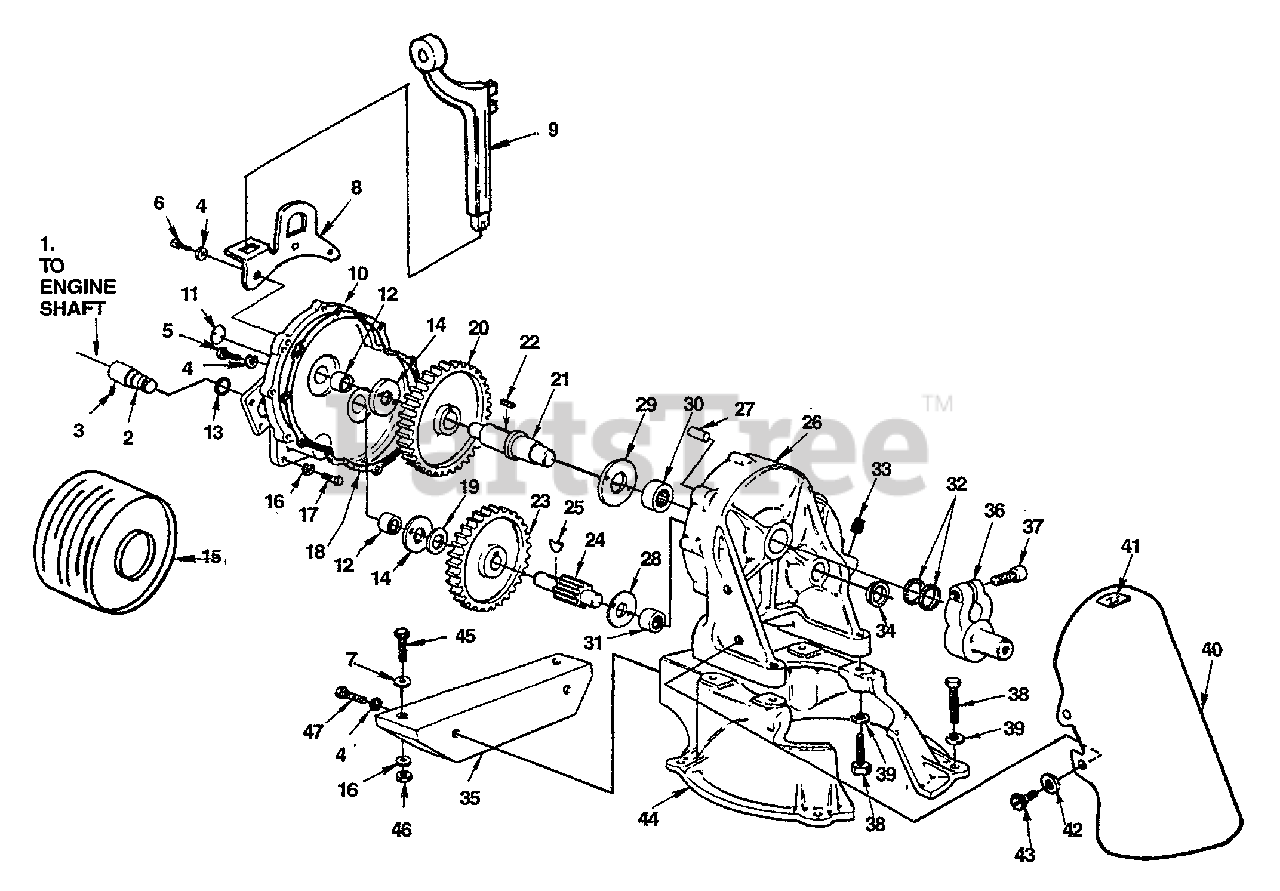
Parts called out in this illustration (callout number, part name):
2	SHAFT - Extension
3	SCREW - set 5/16-18 x 3/8
4	WASHER - lock, 1/4
5	SCREW - hex hd., 1/4-20 x 1
6	SCREW - hex hd.,1/4-20 x 1 1/4
7	WASHER, flat - 5/16
8	BRACKET, lifting
9	WRENCH - Spanner
10	GEAR CASE COVER
11	CAP, bearing
12	BEARING, Needle
13	SEAL, extension shaft
14	WASHER, thrust
15	STRAINER
16	WASHER, lock 5/16
17	SCREW, hex hd., 5/16-24 x 7/8
18	GASKET, gear case
20	GEAR, pump
21	SHAFT, gear
23	GEAR, intermediate
24	SHAFT - pinion
26	GEAR CASE ASSEMBLY
27	PIN, dowel
28	WASHER, thrust
29	WASHER, thrust
30	BEARING, needle
31	BEARING, needle
32	SEAL - Garlock
33	PLUG, pipe
34	CAP - Bearing
35	BRACKET, engine to pump
36	CRANK
37	SCREW, socket hd., 1/2-13 x 1 1/2
38	SCREW, hex hd., 1/2-13 x 1 3/4
39	WASHER, lock 1/2
40	GUARD, pump rod
41	DECAL, grease fitting
42	WASHER, flat
43	SCREW, hex hd., 12-24 x 3/8
44	BODY, pump (upper)
45	SCREW, hex hd., 5/16-18 x 1 3/4
46	NUT, hex 5/16-18
47	SCREW, hex hd. 1/4-20 x 3/4
